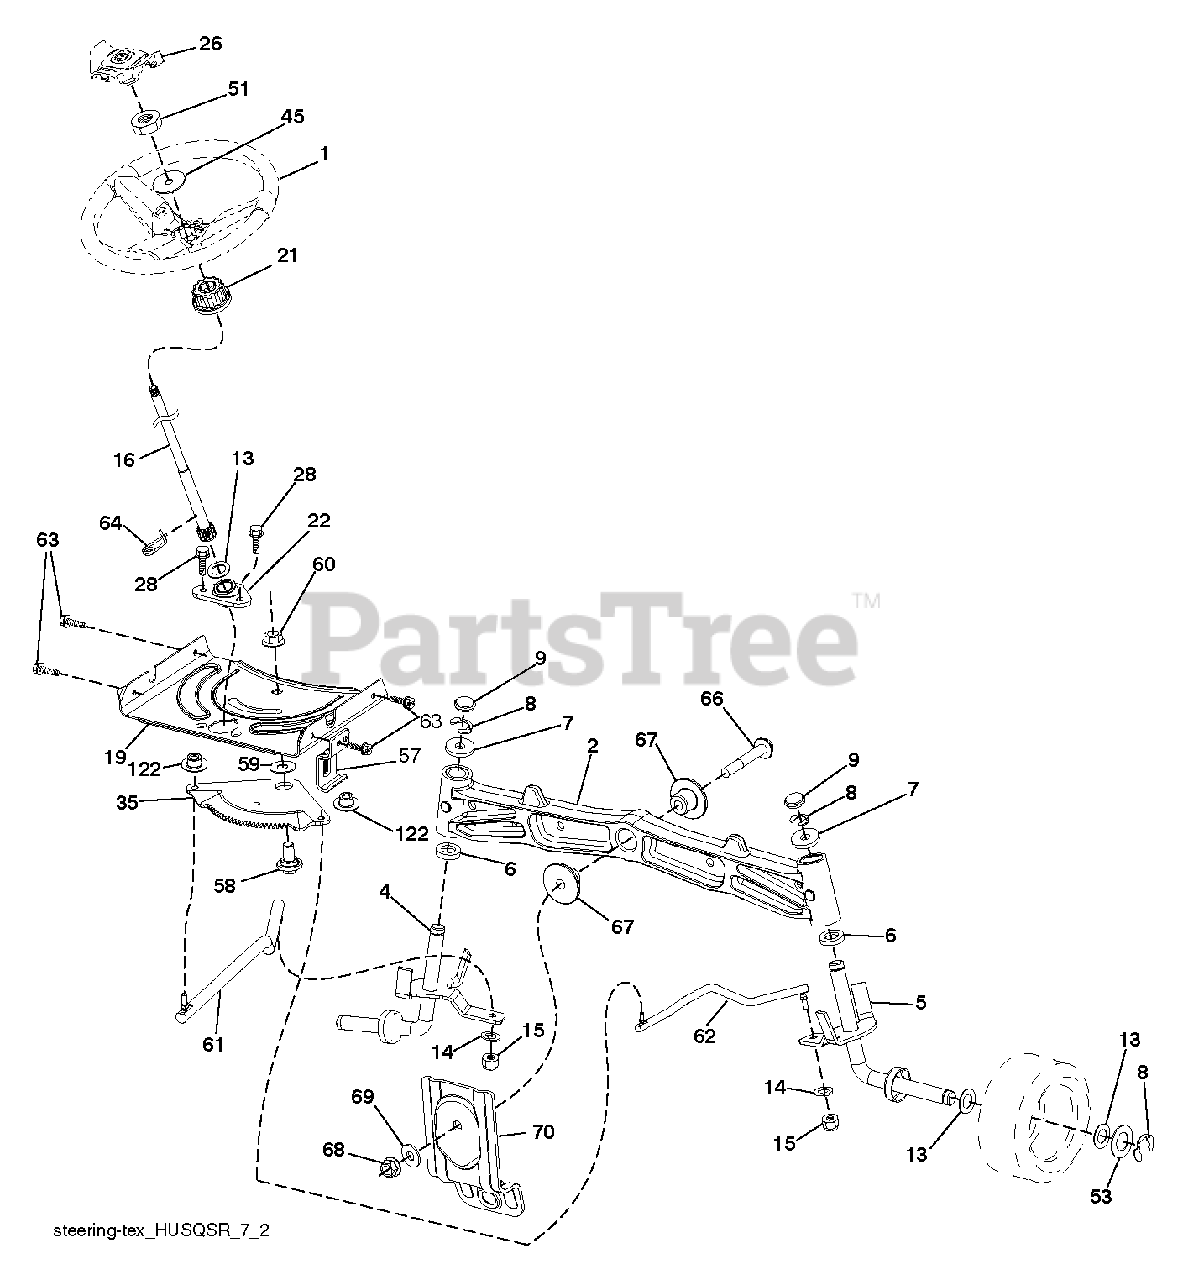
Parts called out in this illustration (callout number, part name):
1	WHEEL.STEER.HUSQ.SR.498.OVMLD
2	AXLE.CAST.IRON
4	SPINDLE.WELDED.LH.16"TEX
5	SPINDLE.WELDED.RH.16"TEX
6	THRUST WASHER
9	CAP.SPINDLE.BLACK
14	WASHER, LOCK 3/8
15	NUT CROWNLOCK 3/8-24
16	SHAFT, STEERING
19	PLATE.STEER.DDL.NLT/NG
21	ADAPTER, WHEEL STNG..
22	STEERING.SUPT.LOWER.
26	INSERT.CAP.WHL.STRG.HUSQ.PREM
28	SCREW, 3/8-16X3/4
35	GEAR.SECTOR.PLATE.DDL.
45	WASHER 9/16"ID, 2 3/8"OD
51	NUT.HEX.1/2-20
53	WASHER.HARDENED
57	BRKT.UPSTOP.GT/LT.TEX
58	BOLT.SHOULDER.SECTOR.P
59	WASHER.THURST.SECTOR.S
60	NUT FLANGE LOCK 5/8-11
61	DRAGLINK.LH.BALLSTUD.D
62	DRAGLINK.RH.BALLSTUD.D
63	SCREW
64	RETAINER.CLIP.SPRING.S
66	BOLT HEX FGHD 7/16-14 X 3 SERR
67	BUSHING.PM.FRONT AXLE
68	NUT.LOCK.FLANGE.7/16
69	WASHER.1.5X.505X.118
70	BRKT.DECK.SUSPENSION.F
122	CAP.GEAR.SECTOR.TEX
